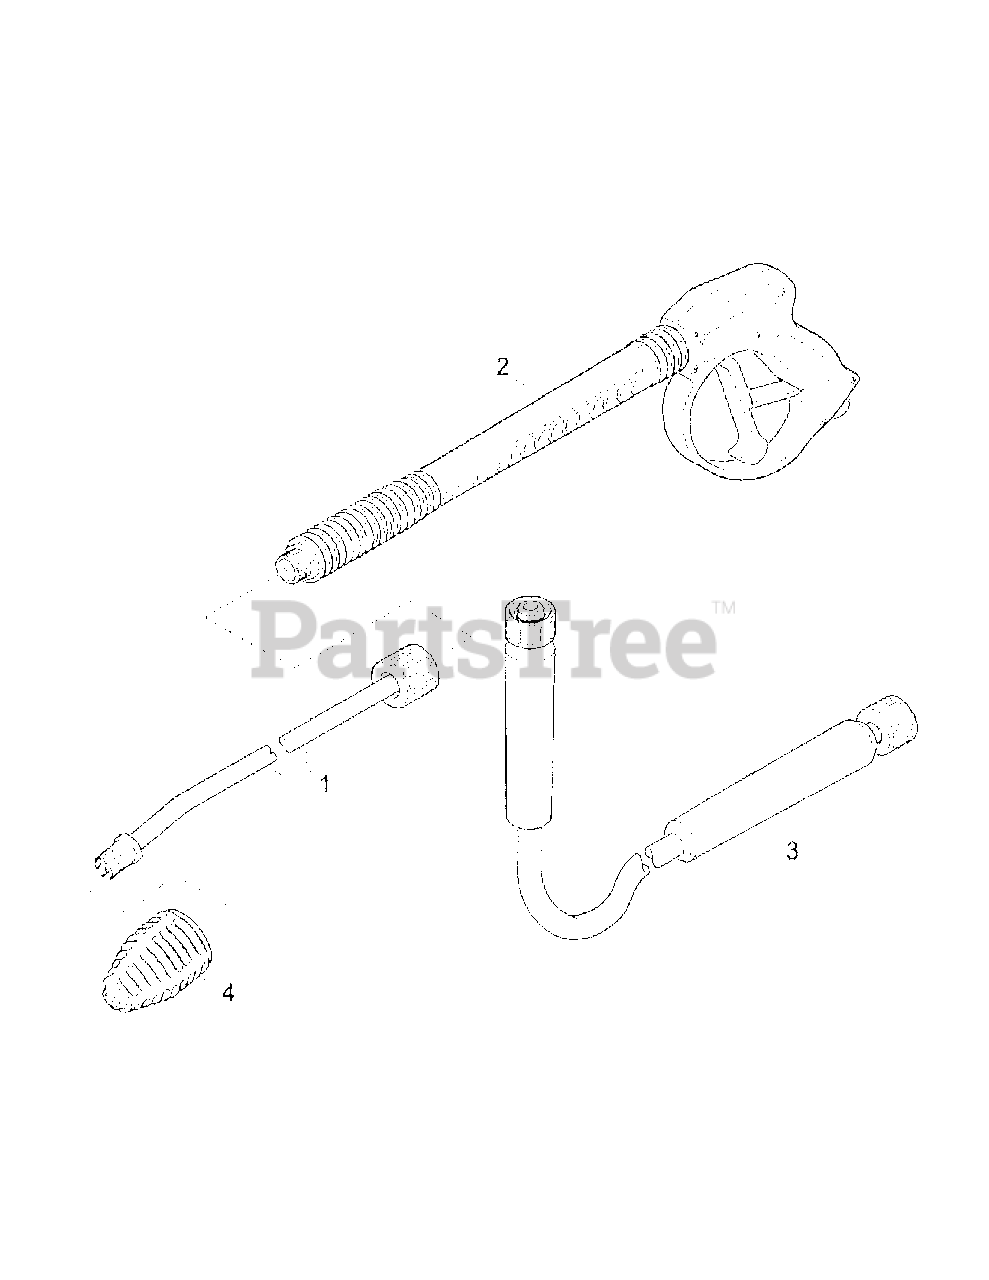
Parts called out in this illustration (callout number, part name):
1	Jet Pipe
2	Trigger Gun
3	High Pressure Hose
4	Rotary Nozzle
